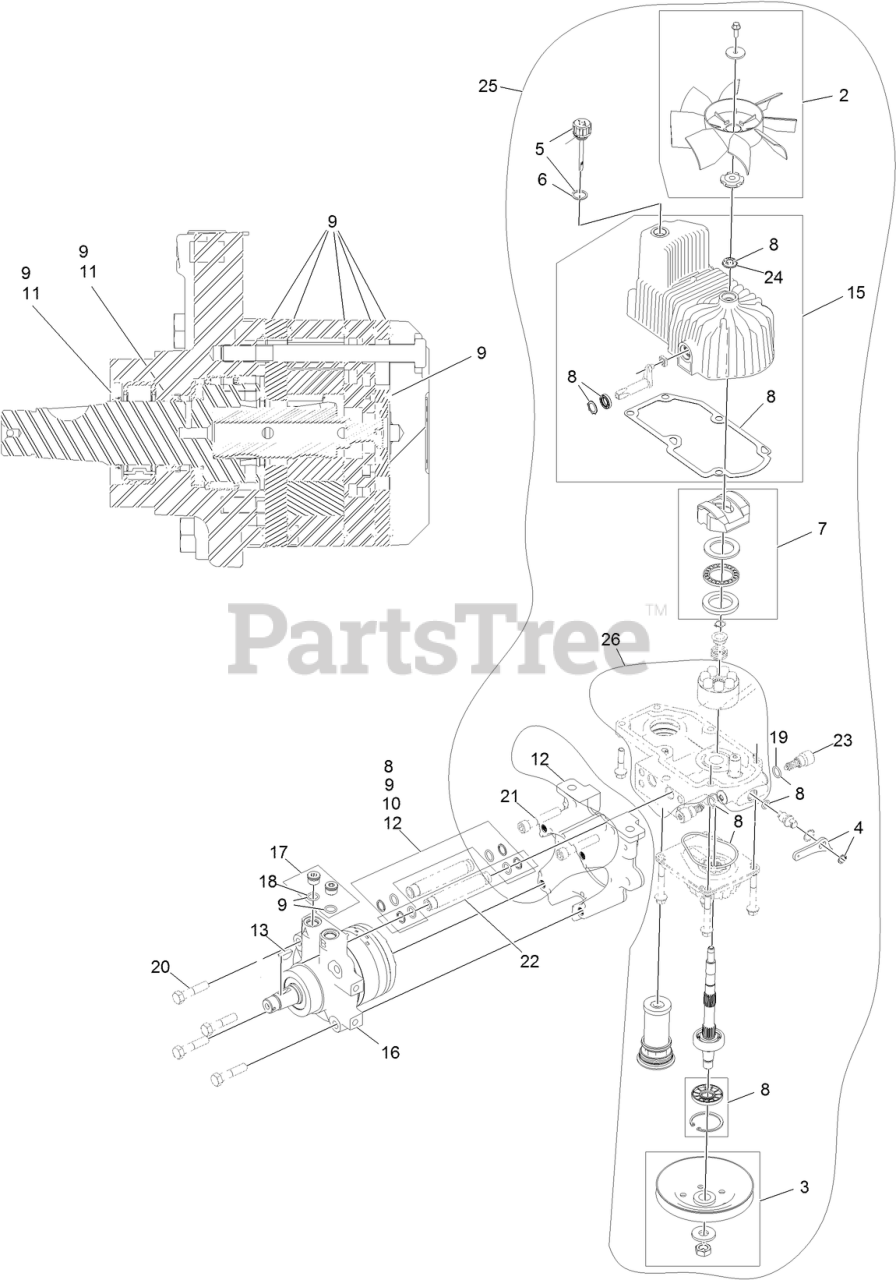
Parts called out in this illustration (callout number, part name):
2	FAN KIT
3	PULLEY KIT
4	HANDLE-BYPASS VALVE, HYDRO
5	DIPSTICK-HYDRO W/GASKET
6	GASKET-DIPSTICK, HYDRO
7	SWASH BLOCK KIT
8	PUMP SEAL KIT
9	MOTOR SEAL KIT
10	TUBE SEAL KIT
11	OUTPUT SHAFT SEAL KIT
12	NOSE CUP-UHT
13	KEY-WOODRUFF
15	HOUSING-HYDRO, LH
16	MOTOR-HYDRAULIC, LH 280CC
17	MAGNETIC PLUGS SERVICE KIT
18	O-RING
19	O-RING-CHECK VALVE
20	SCREW HH
21	SCREW-HSH
22	HYDRAULIC TUBE KIT
23	SHOCK VALVE, 16CC HYDRO
24	SEAL-FAN DRIVE
25	16CC LH PUMP SECTION KIT
26	16CC LH ROTATING GRP KIT
99	PULLER-PULLEY
